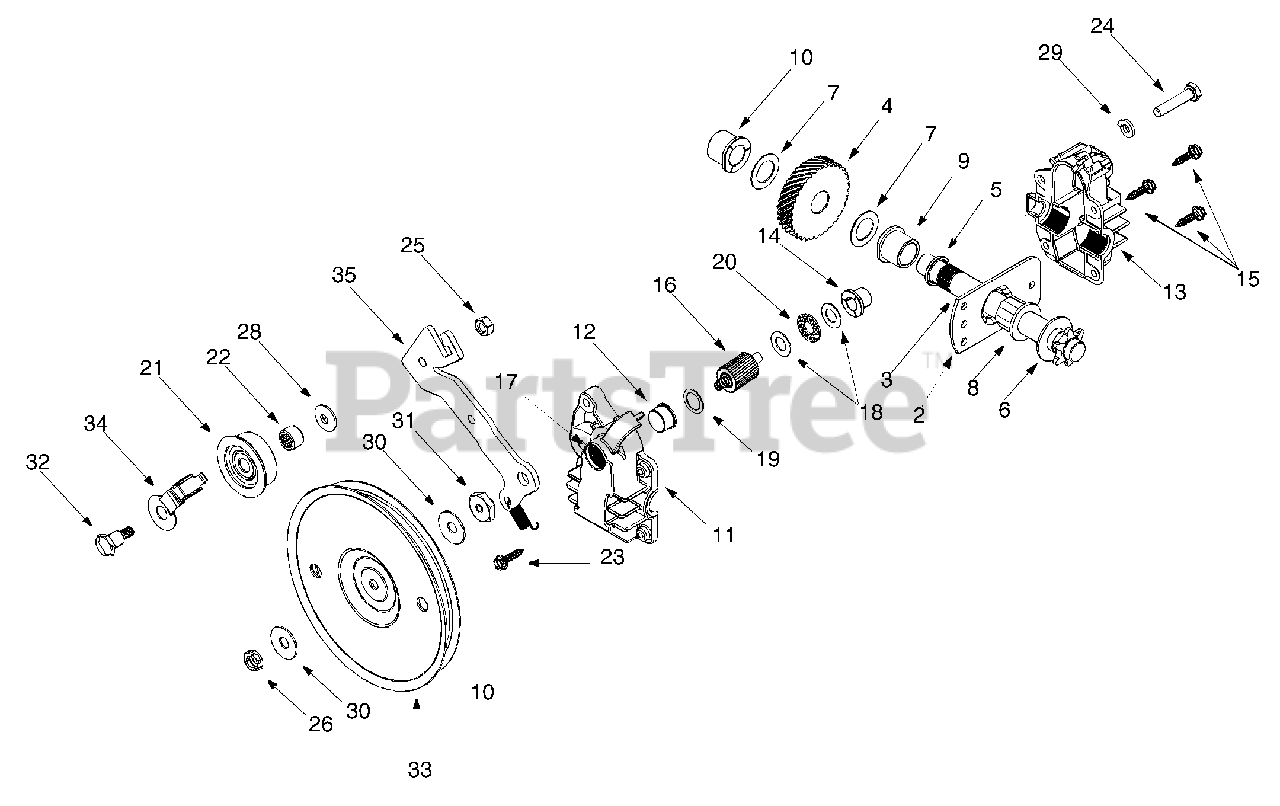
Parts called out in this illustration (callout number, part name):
3	Output Shaft 6T Sprocket
4	Helical 34T Gear
6	Flat Washer .64 ID x 1.24 OD
7	Flat Washer 5/8 x 1.0
8	Hex Flange Bearing .631 ID
9	Flange Bearing .629 ID
10	Flange Bearing .566 ID
11	Lower Housing
12	Flange Bearing .503 ID
13	Upper Housing
14	Flange Bearing .378 ID
15	Hex Washer Screw #10-16 x .75
16	Pinion Shaft 10T
17	Oil Seal
18	Thrust Washer .382 ID x .684 OD
19	Flat Washer .504 ID x .70 OD
20	Thrust Bearing .375 ID x .812 OD
21	Pulley Ass'y Idler w/ Bearing
22	Needle Bearing .375 ID x .375 OD
23	Hex Screw #10-16 x .75
24	Hex Cap Screw 1/4-20 x 1.25
25	Hex Nut 1/4-28
26	Hex Jam Nut 5/16-24 LH Thd
28	Bell Washer .265 ID x .75 OD
29	Lock Washer 1/4
30	Bell Washer .325 ID x .930 OD
31	Shoulder Spacer .375 ID x .165 OD
32	Shoulder Bolt 1/4-28 x .375
33	Flat Pulley 5.06 Dia
34	Belt Keeper
35	Idler Bracket
